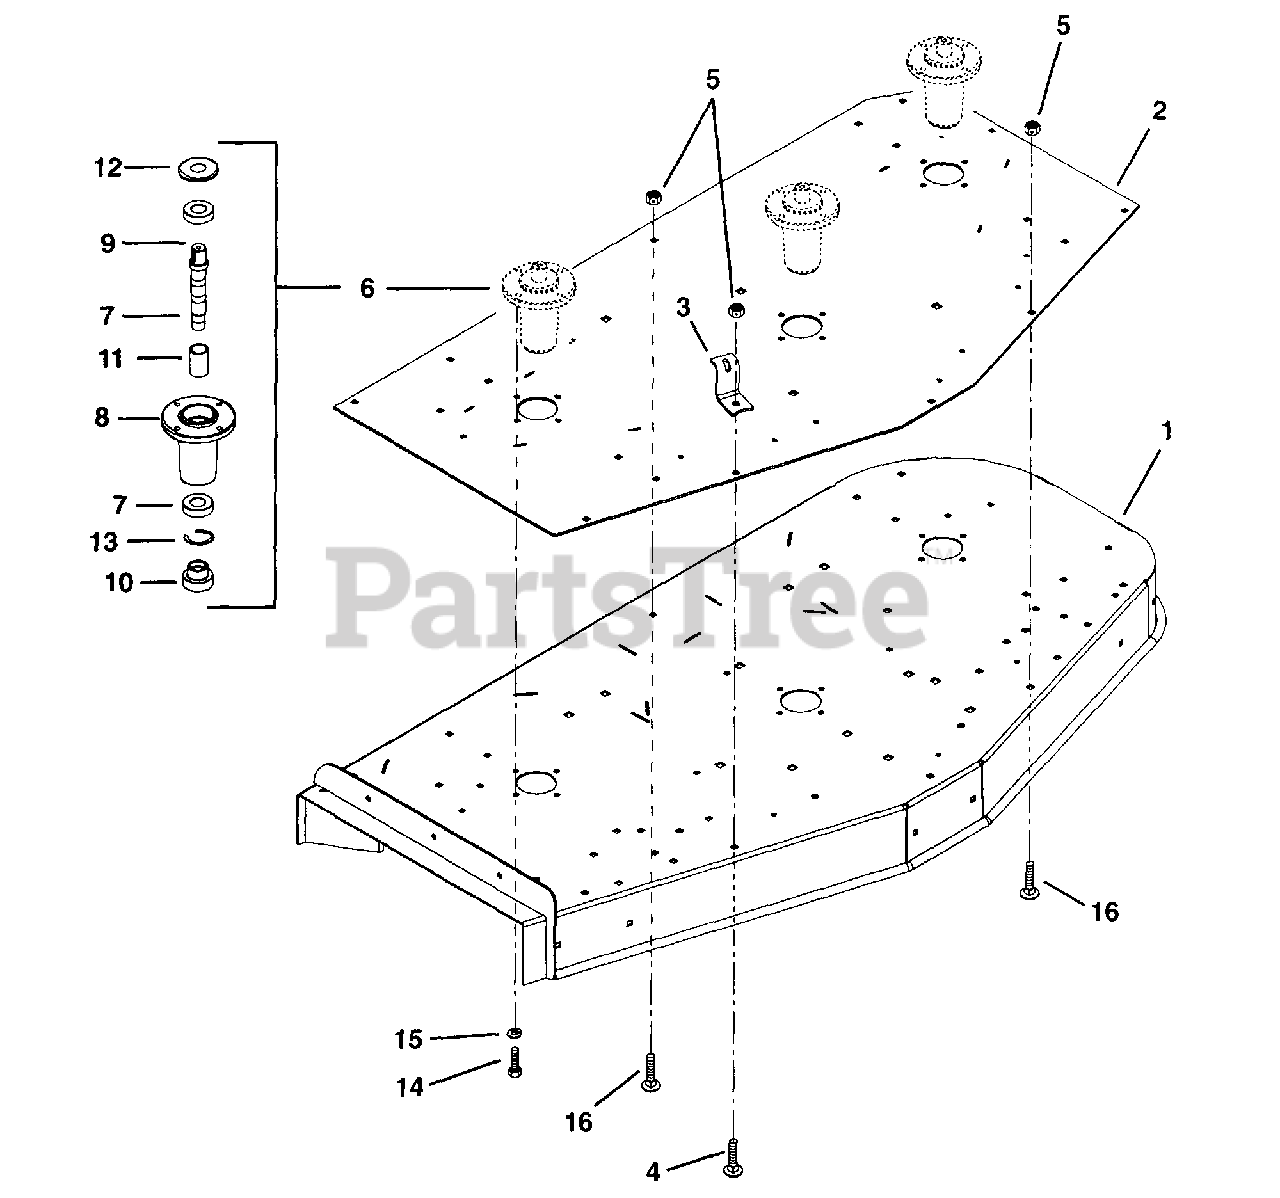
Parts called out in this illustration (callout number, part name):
1	Weldment, 60" Deck (Side Discharge)
2	Plate, 60" Reinforcing
3	Spring, Bracket
4	Bolt-Round Head Square Neck .38-16 x 1.25 Grade 2
5	Nut-Locking-Nylon .38-16
6	Assembly, Spindle L-Hub
7	Bearing-Wide Inner Ring 1.00 x 2.0467
8	Housing-Bearing
9	Shaft-Spindle
11	Spacer 1.010 x 1.250 x 1.845
12	Slinger-Dust
13	Ring, Retaining-Internal 2.210 x .062
14	Bolt-Hex .38-16 x 1.00 Grade 5
15	Washer-Locking .38 x .094
16	Bolt-Round Head Square Neck .38-16 x 1.00 Grade 2
